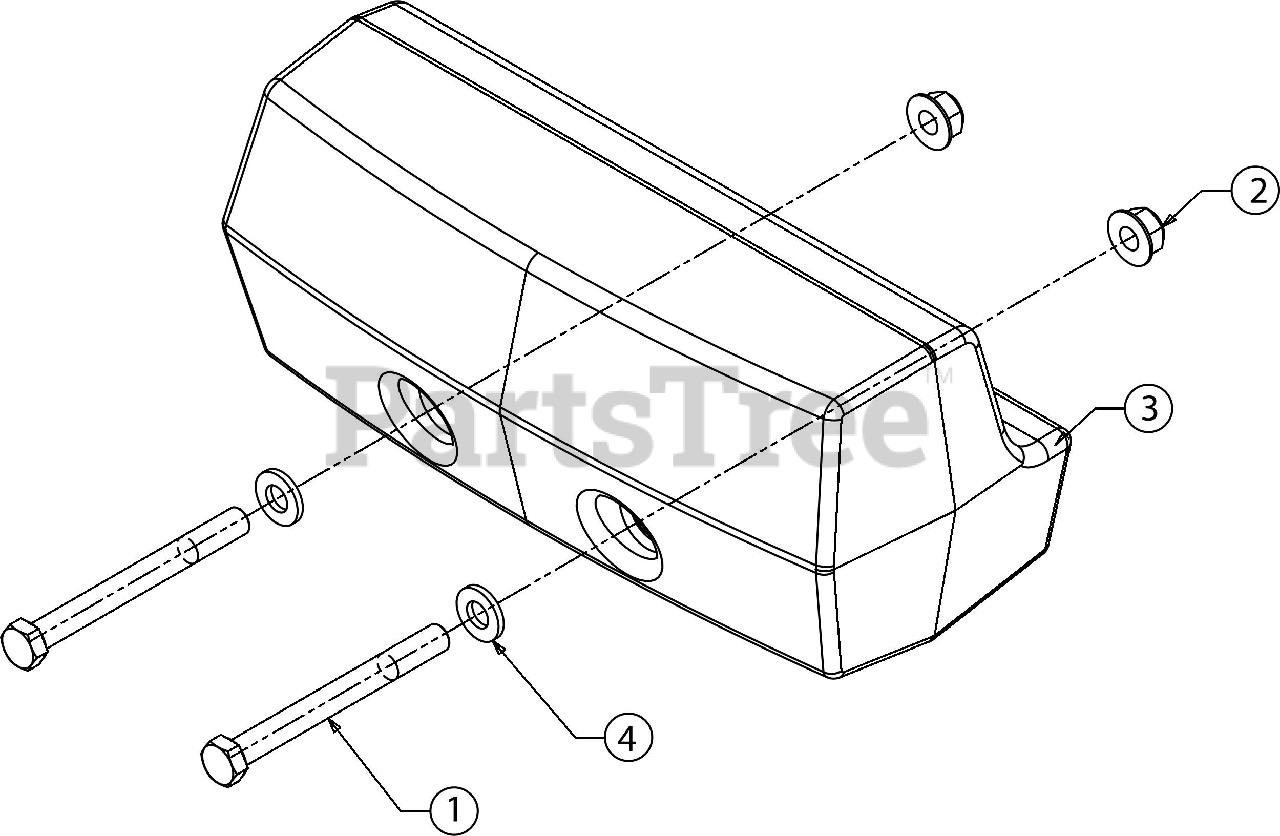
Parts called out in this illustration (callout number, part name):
1	BOLT-HEX 1/2-13X5.0
2	NUT-FLGLK 1/2-13 NYLON
3	COUNTERWEIGHT
4	WASHER-FL
